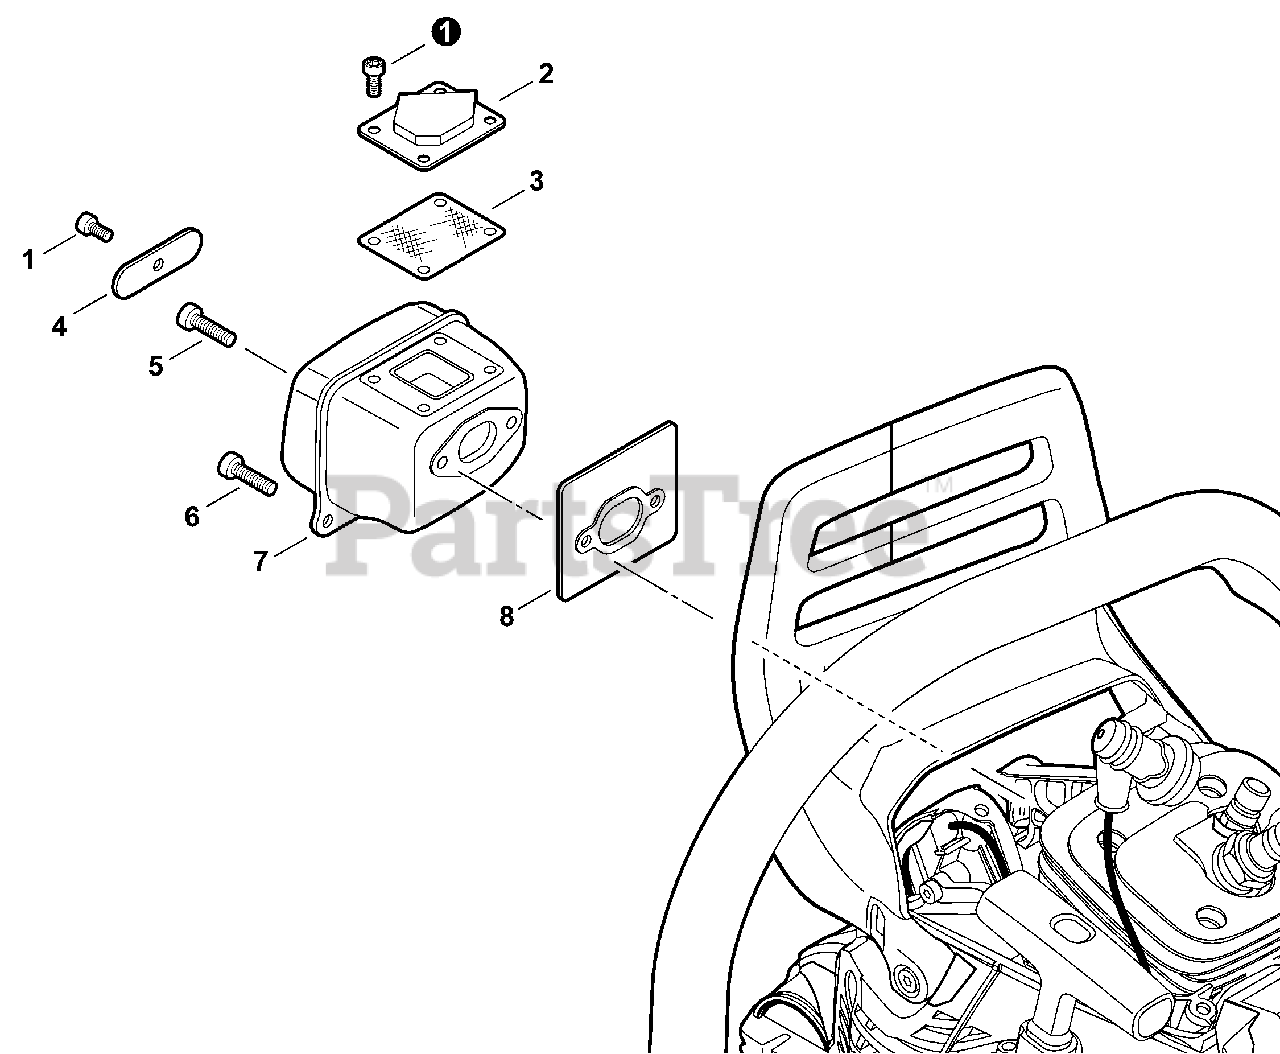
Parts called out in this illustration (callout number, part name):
1	BOLT, TORX 4
2	GUIDE, EXHAUST
3	SCREEN, ARRESTOR
4	PLATE, MUFFLER
5	BOLT, TORX 5
6	BOLT, TORX 5
7	MUFFLER, EXHAUST
8	GASKET,EXHAUST
